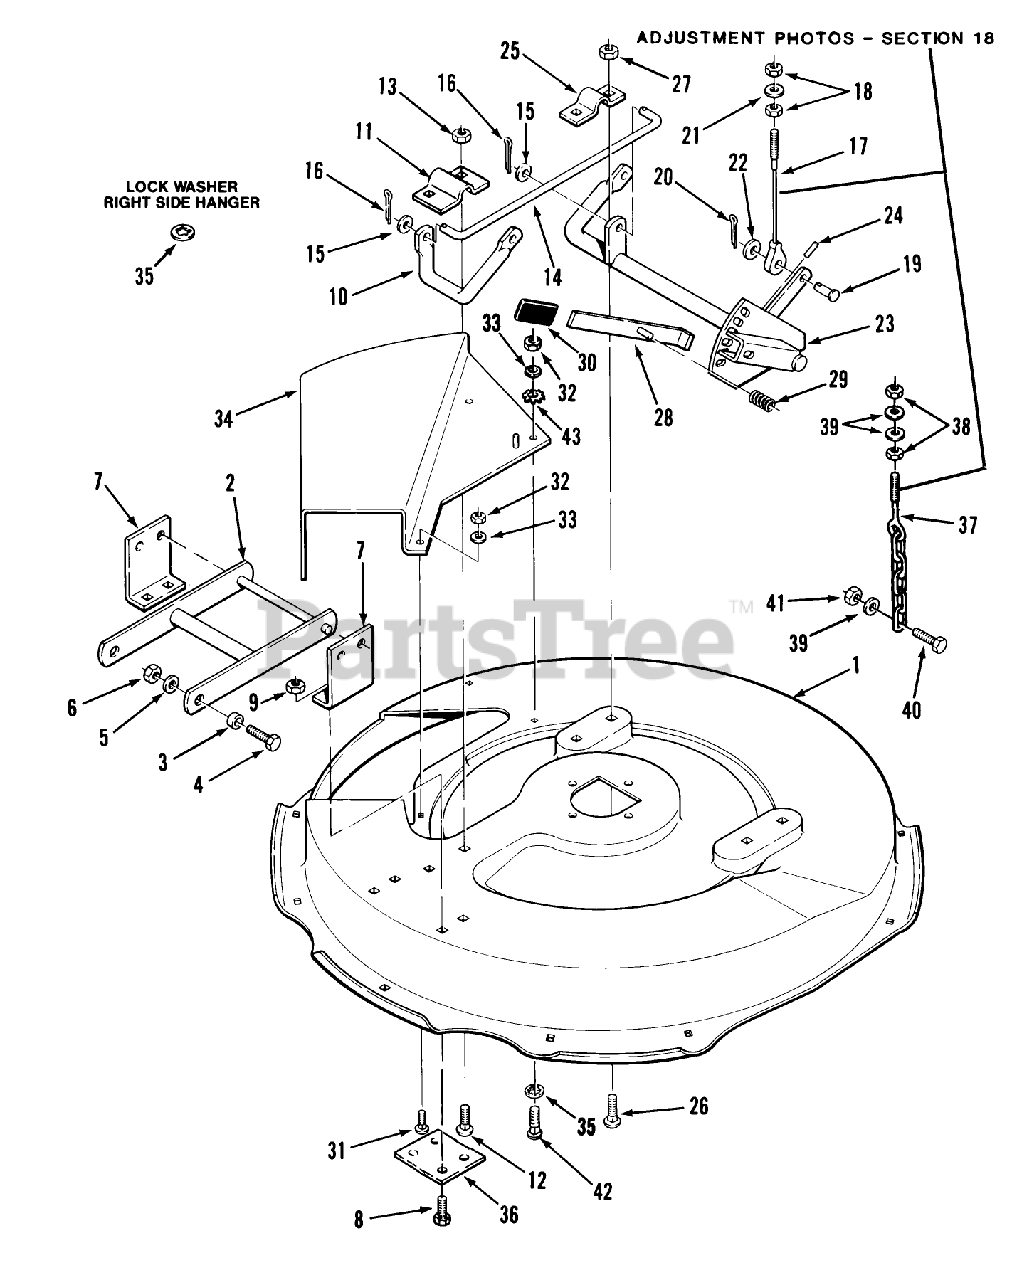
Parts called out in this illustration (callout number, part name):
3	SPACER
7	BRKT FRONT MOWER *R
17	CABLE MOWER SUPPORT
21	WASHER 5/16 SAE
24	SPIROL PIN
25	CLAMP
28	LEVER ASSY
29	SPRING-COMPRESSION
39	WASHER 5/16 SAE
